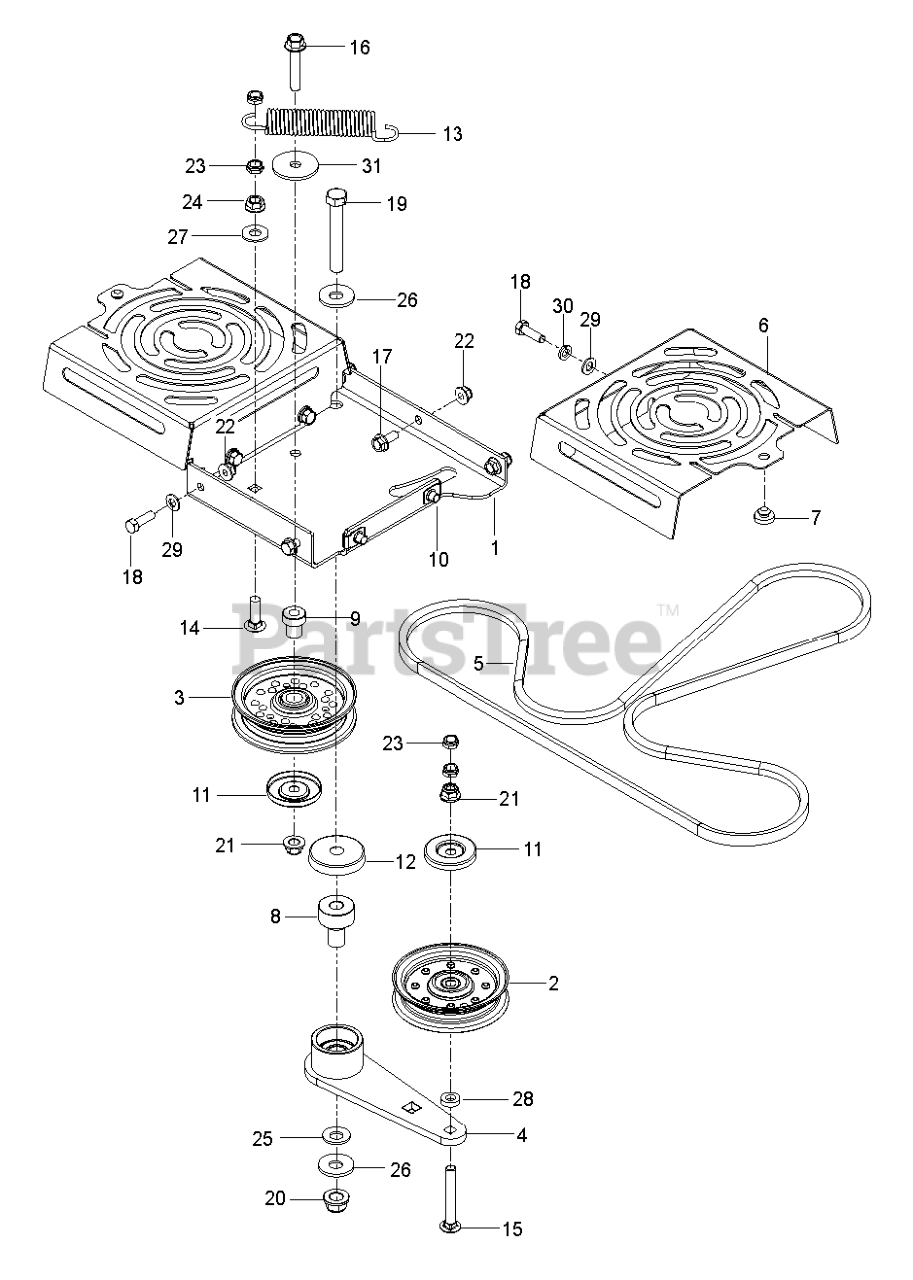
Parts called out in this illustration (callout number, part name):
1	PLATE.PNT.IDLER.SUPPORT.E-DIP
3	PULLEY.IDLER.FLAT.46.PR.DR.
4	ARM, IDLER, STEEL, W/BGS
5	BELT, HYDRO, 3400
6	SHIELD FAN BLACK
7	GROMMET, BUMPER
8	PIVOT, BEARING
9	PIVOT, IDLER
10	U-CLIP 5/16-18 NUT RETAINER
11	SHIELD DUST
20	NUT 1/2-13 HEX FLANGE NYLOK CL
22	NUT HEXAGON FLANGE 5/16-18 ST
27	GSPW Washers
28	WASHER 3/8 X 3/4 X .187 TK
29	WASHER 11/32 X 11/16 X 14 GA T
30	WASHER SPRING LOCK WASHER WITH
